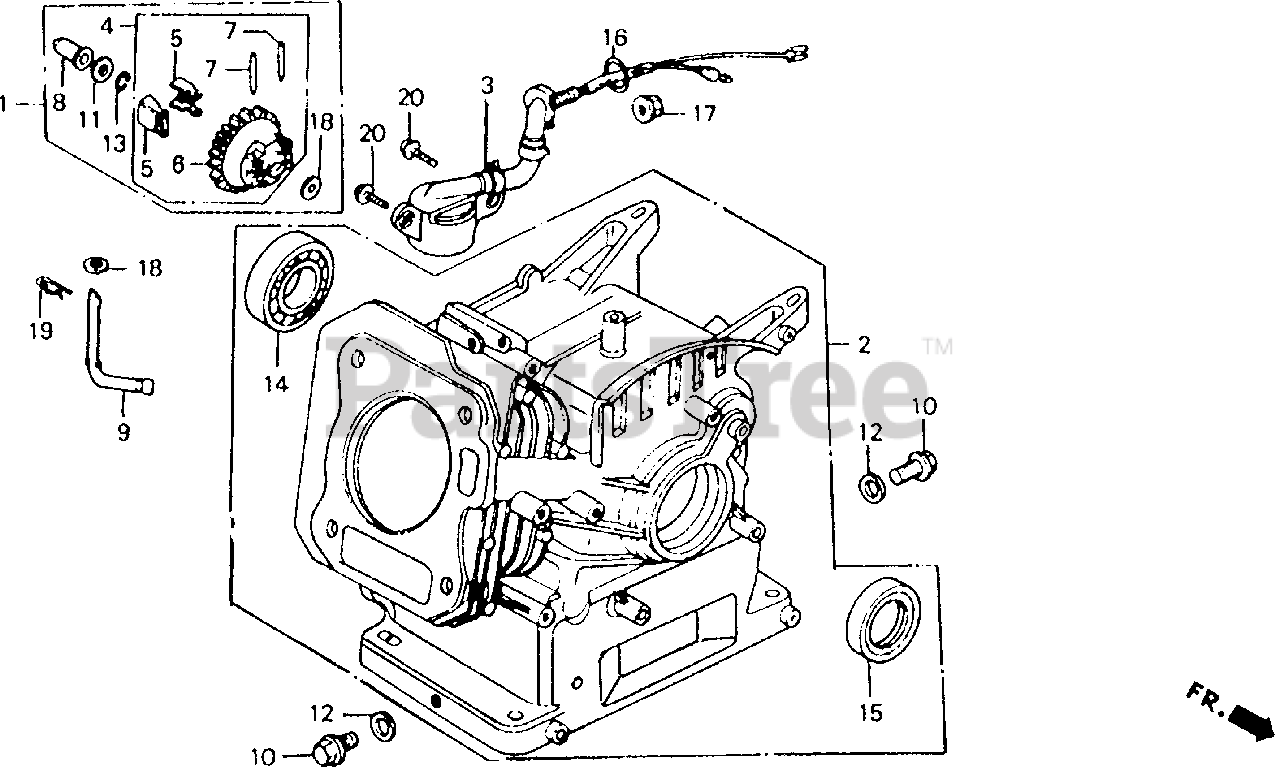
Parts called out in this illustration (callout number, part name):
1	GOVERNOR KIT
2	CYLINDER ASSY.
2	CYLINDER ASSY. (STD)
4	GOVERNOR ASSY.
5	WEIGHT, GOVERNOR
6	HOLDER, GOVERNOR WEIGHT
7	PIN, GOVERNOR WEIGHT
8	SLIDER, GOVERNOR
9	SHAFT, GOVERNOR ARM
10	BOLT, DRAIN PLUG
11	WASHER, THRUST (6MM)
12	WASHER, DRAIN PLUG (10.2MM)
13	CLIP, GOVERNOR HOLDER
14	BEARING, RADIAL BALL (62/22)
15	OIL SEAL (22X35X6)
18	WASHER, PLAIN (6MM)
19	PIN, LOCK (8MM)
